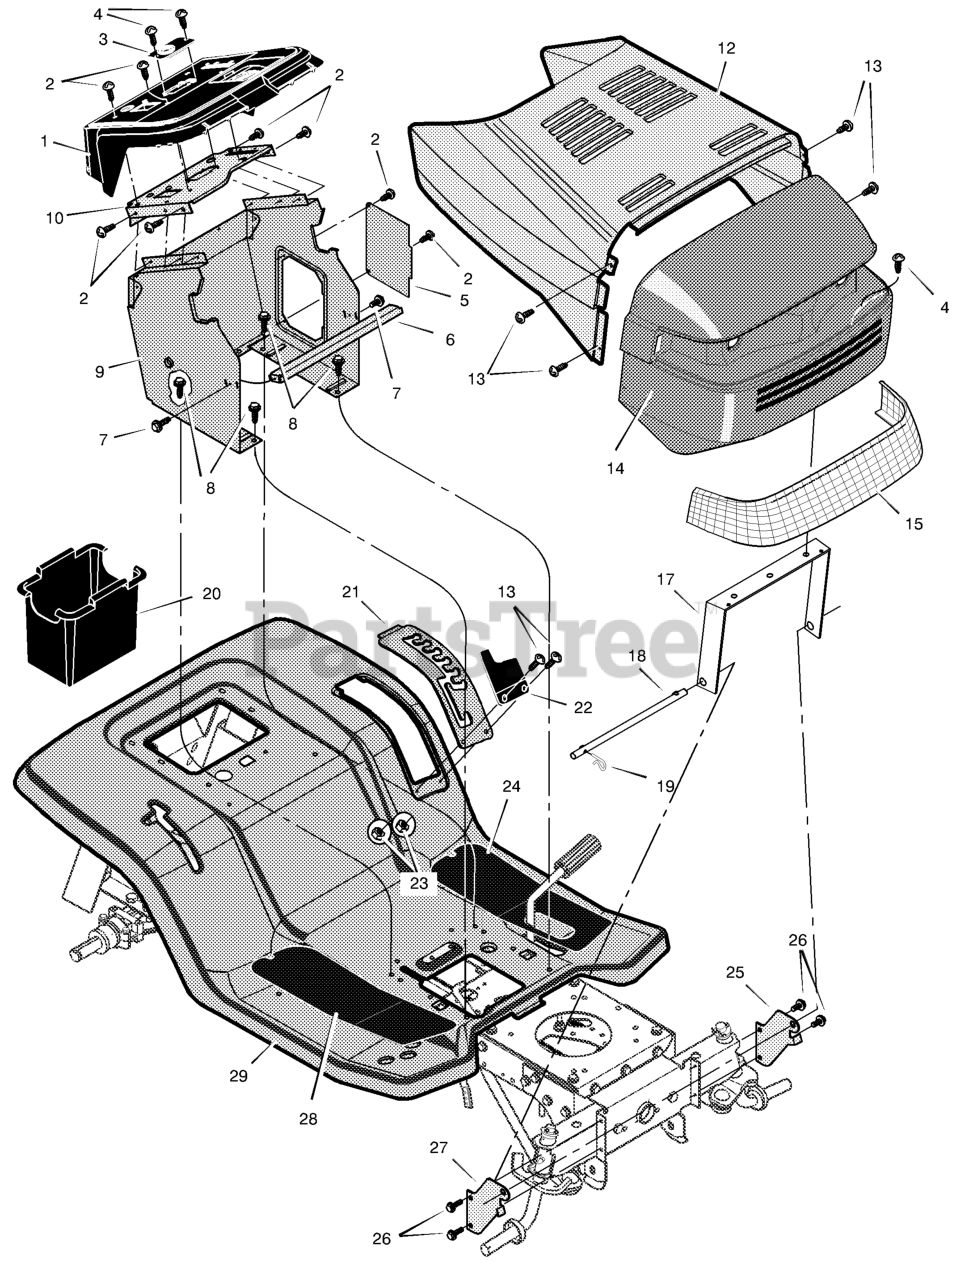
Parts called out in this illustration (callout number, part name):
2	Screw
3	Bearing, Upper Steering
5	Panel, Side Access
6	Channel, Support
9	Support, Dash
10	Plate, Dash
13	Bolt, Shoulder
14	Grille
15	Lens, Right
17	Brace, Grille
18	Rod, Pivot
19	Pin, Hair
20	Container, Battery
21	Plate, Lift Detent
24	Mat, Left
25	Support, Left Grille
27	Support, Right Grille
28	Mat, Right
29	Deck, Seat
